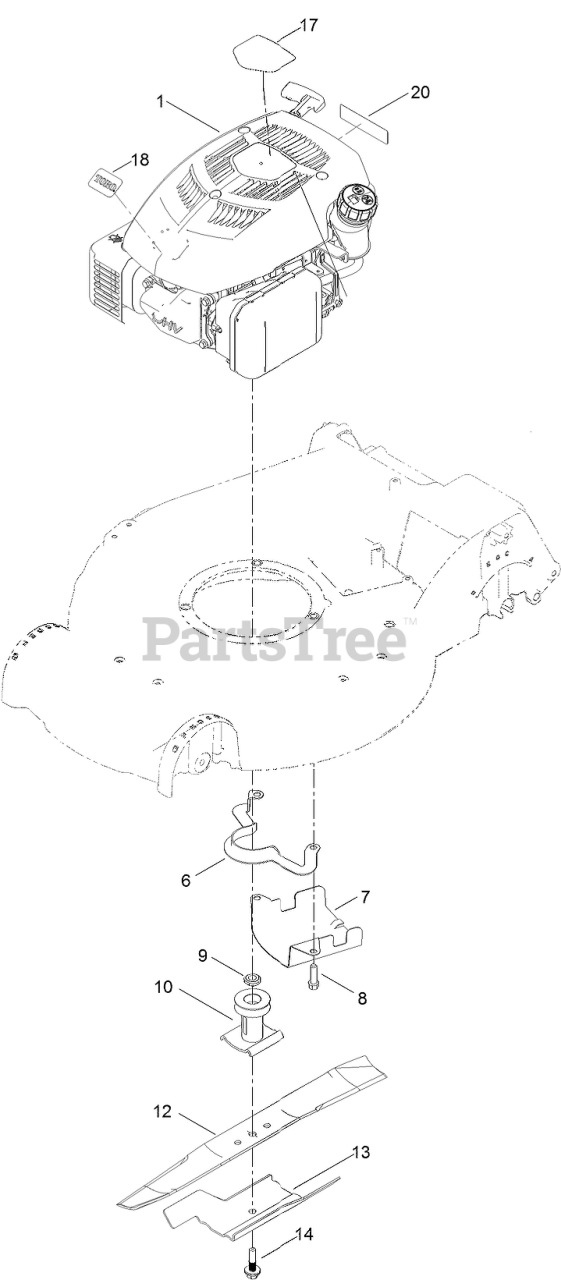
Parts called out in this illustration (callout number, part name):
1	ENGINE-1P65F-2
6	GUIDE-BELT
7	SHIELD-GRASS
8	SCREW-TAPTITE
9	SPACER-DRIVER
10	DRIVER-BLADE
12	BLADE-21IN, RECYCLING
13	ACCELERATOR-BLADE
14	BOLT-BLADE
17	DECAL-SHROUD
20	DECAL-ARRESTER, SPARK
